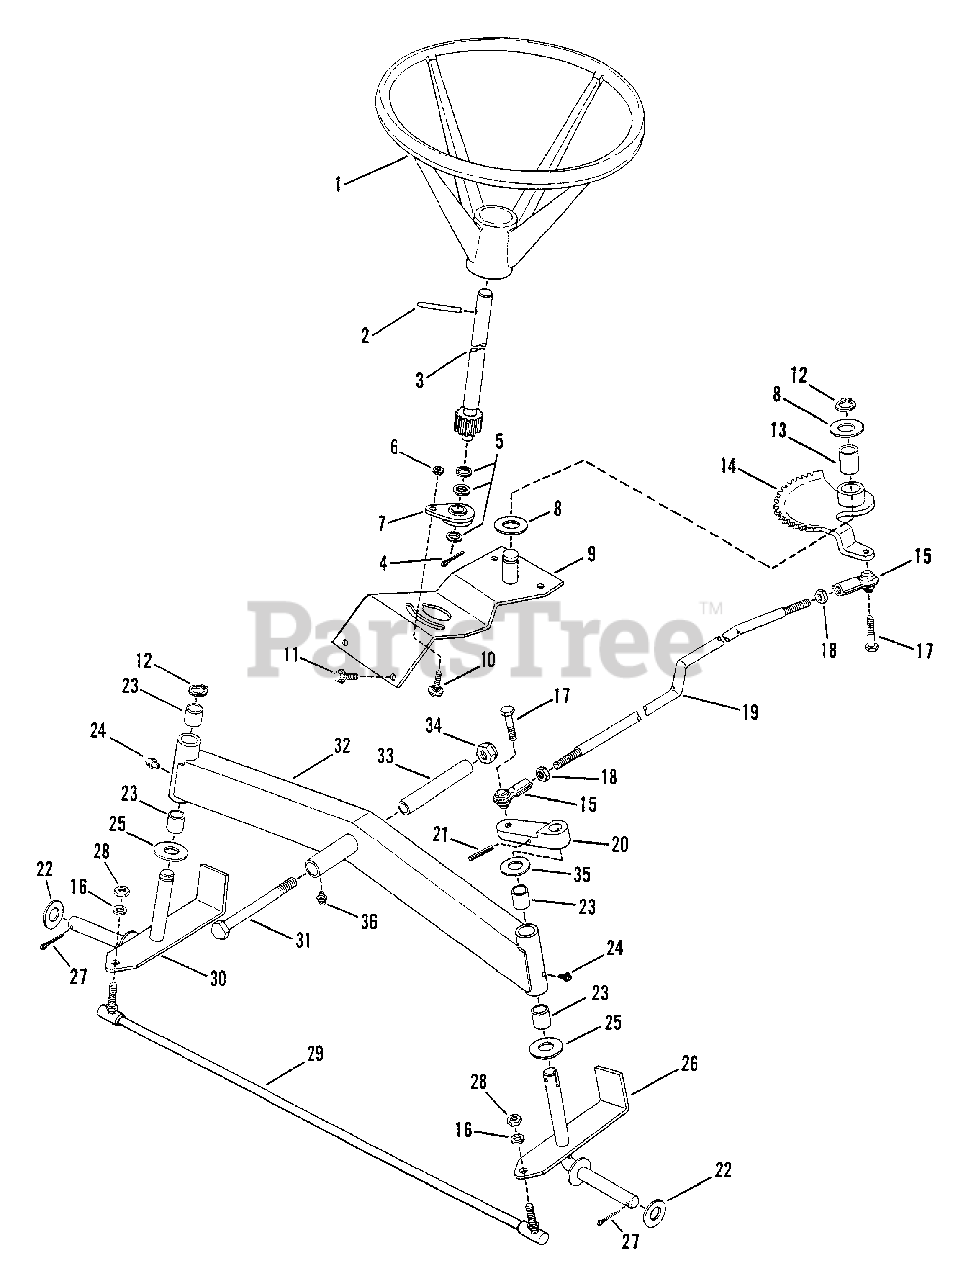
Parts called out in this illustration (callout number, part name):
1	WHEEL, Steering
2	PIN, 1/4 x 2-1/4" Roll
3	SHAFT, Steering
4	PIN, Cotter 3/32 x 1"
5	WASHER, 1/2 x 3/4" Dia. Shim
6	NUT, 1/4-20 Hex Flange Lock
7	ADJUSTER, Steering
8	WASHER, Thrust
9	ASSEMBLY, Steering Support
10	BOLT, 1/4-20 x 5/8" Short Neck Carriage
11	SCREW, 5/16-18 x 5/8" Self-Tapping
12	RING, Retaining
13	BEARING
14	ASSEMBLY, Sector
15	BALL JOINT, Drag Link 3/8-24
16	WASHER, 3/8 Split Lock
17	SCREW, 318-24 x 1 1/4" Hex Head Cap
18	NUT, 3/8-24 Hex Jam
19	DRAG-LINK
20	ARM, Steering
21	PIN, 1/4x1-1/4" Roll
22	WASHER, 49/64 x 1-1/2" Dia. Flat
23	BEARING, Sleeve
24	LUBE FITTING, Straight (press-fit for .187 dia. Hole)
25	WASHER, Thrust
26	ASSEMBLY, Spindle (Left Hand)
27	PIN, 5/32 x 1" Cotter
28	NUT, 3/8-24 Hex
29	TIE-ROD
30	ASSEMBLY, Spindle (Right Hand)
31	SCREW, 1/2-20 x 4 1/2" Hex Head Cap
32	ASSEMBLY, Front Axle
33	SPACER, Axle Pivot
34	NUT, 1/2-20 Hex Lock
35	WASHER, 314 x 1-1/8" Dia.
36	FITTING, Lube
